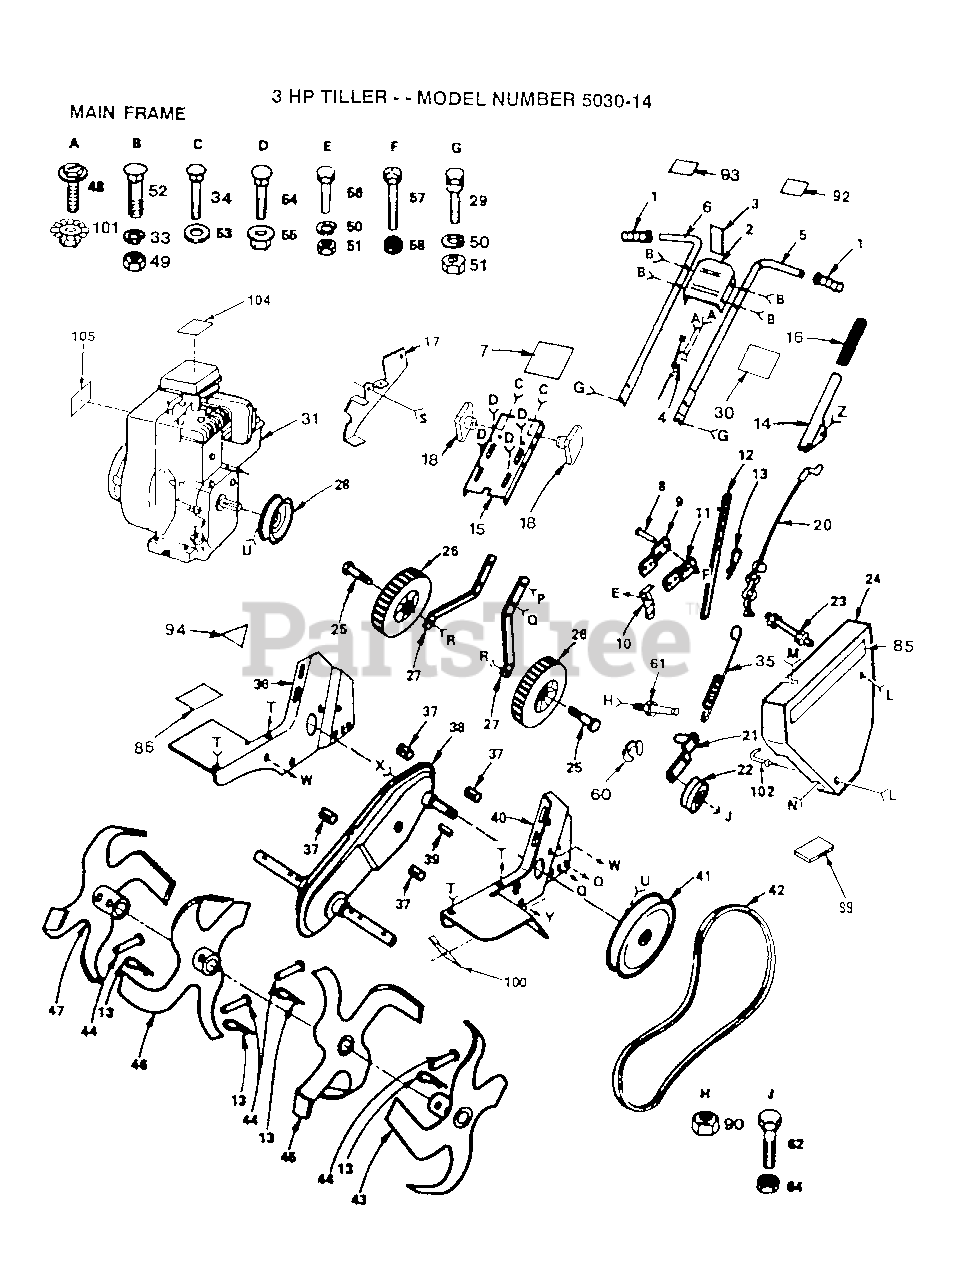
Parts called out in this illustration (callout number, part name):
3	DECAL, THROTTLE
7	"DECAL,PANEL HANDL"
8	DRILLED RIVET RT
9	STAKE.SUPT.TILLER
10	STAKE SPRING CT
13	SPRING.RETAINER
15	"PANEL,HANDLE"
16	GRIP T
21	IDLER ARM TI
23	BOLT TI
25	BOLT SHOULDER
30	DECAL, HANDLE BRACKET
31	ENGINE - 3HP - BRIGGS & STRATTON
33	WASHER
34	BOLT
35	SPRING EXT TI
36	"BRKT,ENG RH"
37	SPLIT SPACER RT
39	KEY T
41	TRANS SHEAVE RT
43	TINE ASS'Y LH
44	DRILLED RIVET RT
45	TINE INN LH TI
46	TINE ASSY, INNER
47	TINE ASSY RH
48	SCREW
50	LOCKWASHER
51	NUT.HEX.5/16-18
52	BOLT
53	WASHER
54	BOLT
55	NUT
56	BOLT
57	BOLT.3/8-24X1-1/2
58	GRIPCO NUT
60	KLIP RING TI
61	SHAFT IDLER TI
64	NUT
85	DECAL, BELT GUARD
90	JAM NUT TI
92	DECAL TI
93	DECAL TI
94	DECAL - OPEI
99	PAD IDLER TI
100	SHIELD-DIRT TI
104	DECAL TI
105	"DECAL,ENG HP"
